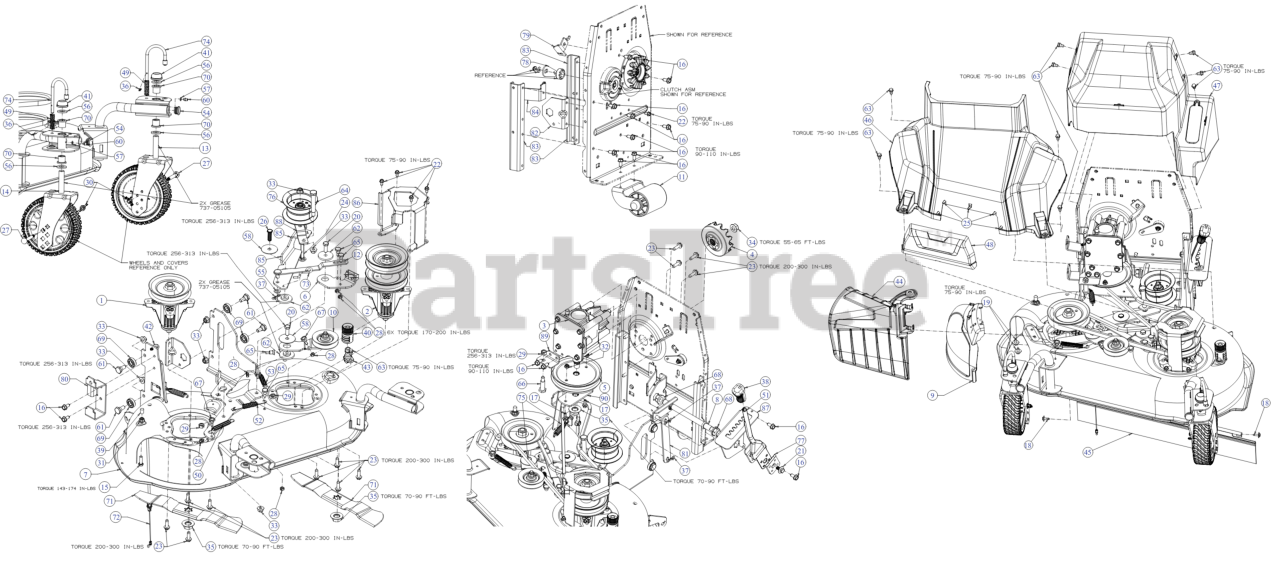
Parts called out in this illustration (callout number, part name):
1	SPINDLE ASSEMBLY W/PULLEY 5.08 DIA
2	SPINDLE ASSEMBLY-W/PULLEY 5.08 DIA
3	ANGLE GEARBOX
4	DOG CLUTCH ASSEMBLY
5	DRIVE PULLEY 6.03 DIA
6	DECK BRACKET ASSEMBLY
8	DECK LIFT ASSEMBLY
9	MULCH PLUG ASSEMBLY
10	PULLEY BRACKET ASSEMBLY
12	BRAKE WELD ASSEMBLY
13	CASTER BRACKET ASSEMBLY (LH) (MTD RED)
14	CASTER BRACKET ASSEMBLY (RH) (MTD RED)
15	SCREW 5/16-18 x 1.0 GR5
16	SCREW 5/16-18 x .750
17	SCREW 1/4-20 x .75 GR5
18	SCREW 10-16 x .625
19	SCREW 1/4-20 x .50
20	SCREW 3/8-16 x 1 GR5
21	SCREW 5/16-24 x .750 GR5
22	SCREW 1/4-20 X.500
23	SCREW 5/16-18 x 1.00
24	BOLT 3/8-16X2.25 GR5
25	SCREW 1/4-10 x .750
26	SCREW 3/8-16 x 1.25 GR5
27	AXLE CASTER
28	HEX LOCK NUT
31	FLANGE LOCK NUT 5/16-18
32	FLANGE LOCK NUT
35	FLANGE NUT 5/8-18
36	COTTER PIN .072 DIA. 1.13 LG
37	BOW TIE COTTER PIN 1/4-5/16
38	HANDLE GRIP
40	WATER NOZZLE ADAPTER
42	CABLE RETAINER CLIP
43	DECK WASH NOZZLE
44	CHUTE DEFLECTOR
45	TRAILSHIELD 23.00
46	LOWER COVER DECK 28"
47	UPPER COVER DECK 28"
48	LOWER COVER
49	COMPRESSION SPRING .531 OD 1.75 LG
50	EXTENSION SPRING
51	DECK HEIGHT LEVER
52	EXTENSION SPRING
53	EXTENSION SPRING
55	FLAT WASHER
56	FLAT WASHER
57	FLAT WASHER
58	HUB CAP WASHER .406 x 1.92 x .060
60	GREASE FITTING
61	SHOULDER SCREW .498 DIA x .340
62	SHOULDER SPACER
63	SHOULDER SCREW 1/4-20 x .50
64	SHOULDER SCREW .500X 2.62: 3/8-16
65	SHOULDER SCREW .375 x X .380 x 1/4-20
66	SHOULDER SCREW .50
67	SHOULDER SCREW .37
68	FLANGE BEARING
69	BALL BEARING
70	BEARING:FLANGE .631 ID
71	14.20" BLADE (MULCH)
71	Cub Cadet 28" BLADE SET
71	Genuine Factory Parts 28" BLADE SET
72	DECK CABLE
75	V-BELT A SEC 43.10
76	IDLER PULLEY
77	HEIGHT LEVER BRACKET
78	DECK CABLE BRACKET
79	DECK CABLE BRACKET
80	GRASSBAG BRACKET (POWDER BLACK)
81	LIFT LINK BRACKET(POWDER BLACK)
82	LIFT BRACKET (POWDER BLACK)
84	KEEPER BRACKET (POWDER BLACK)
85	DRIVE ENGAGEMENT BRACKET
86	BELT KEEPER BRACKET
87	HEIGHT ADJUSTMENT BRACKET
88	KEEPER BRACKET (POWDER BLACK)
89	KEEPER BRACKET (POWDER BLACK)
90	GEAR BOX SPACER
